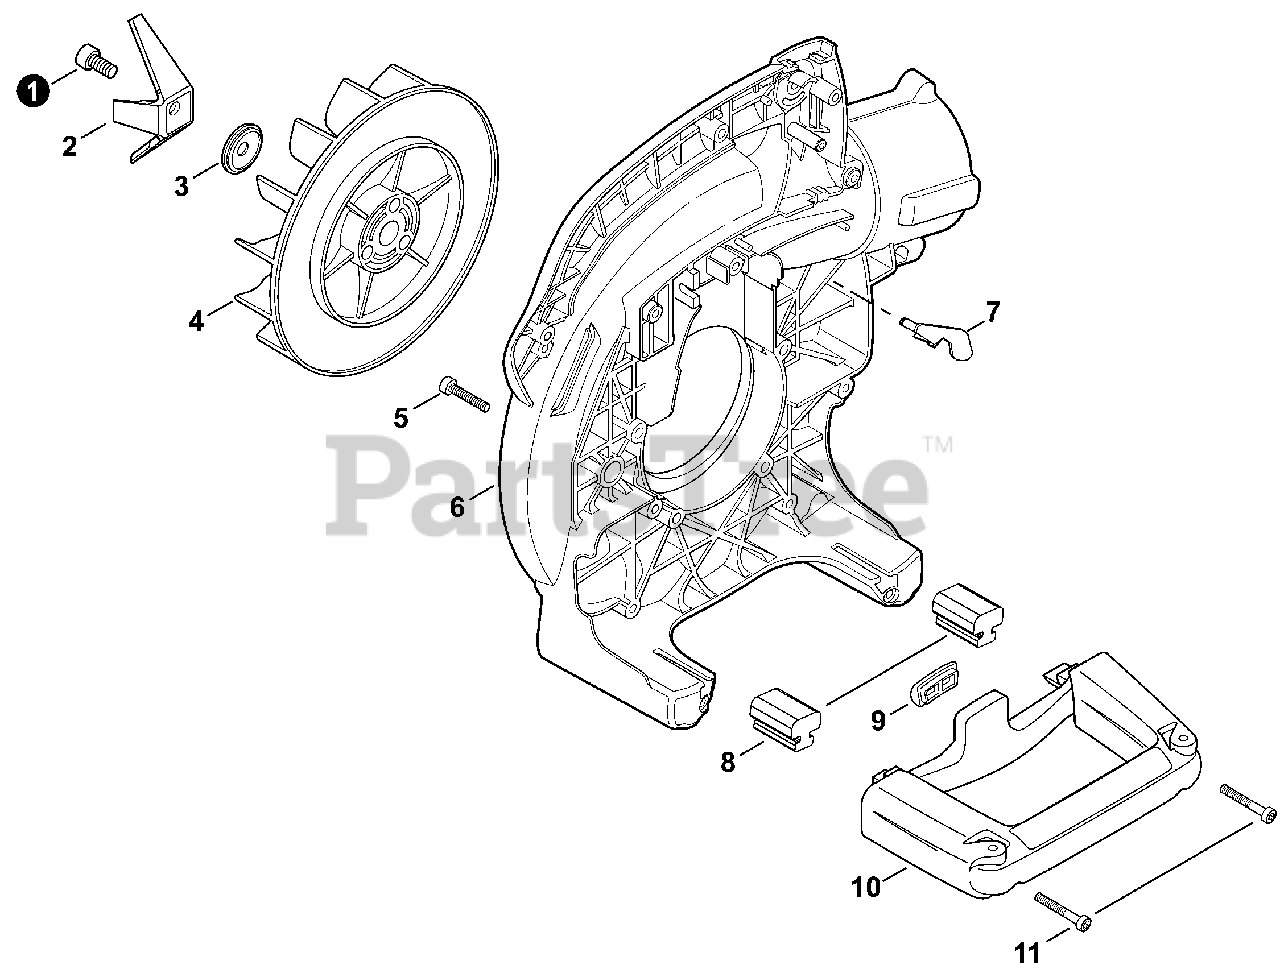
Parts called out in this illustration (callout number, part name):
1	BOLT 8×15
2	CUTTER, SHREDDER
3	WASHER 8.2×31×0.8
5	BOLT, TORX 4×20
6	CASE, FAN
9	CUSHION
10	HANDLE, REAR
11	BOLT, TORX 5×25
